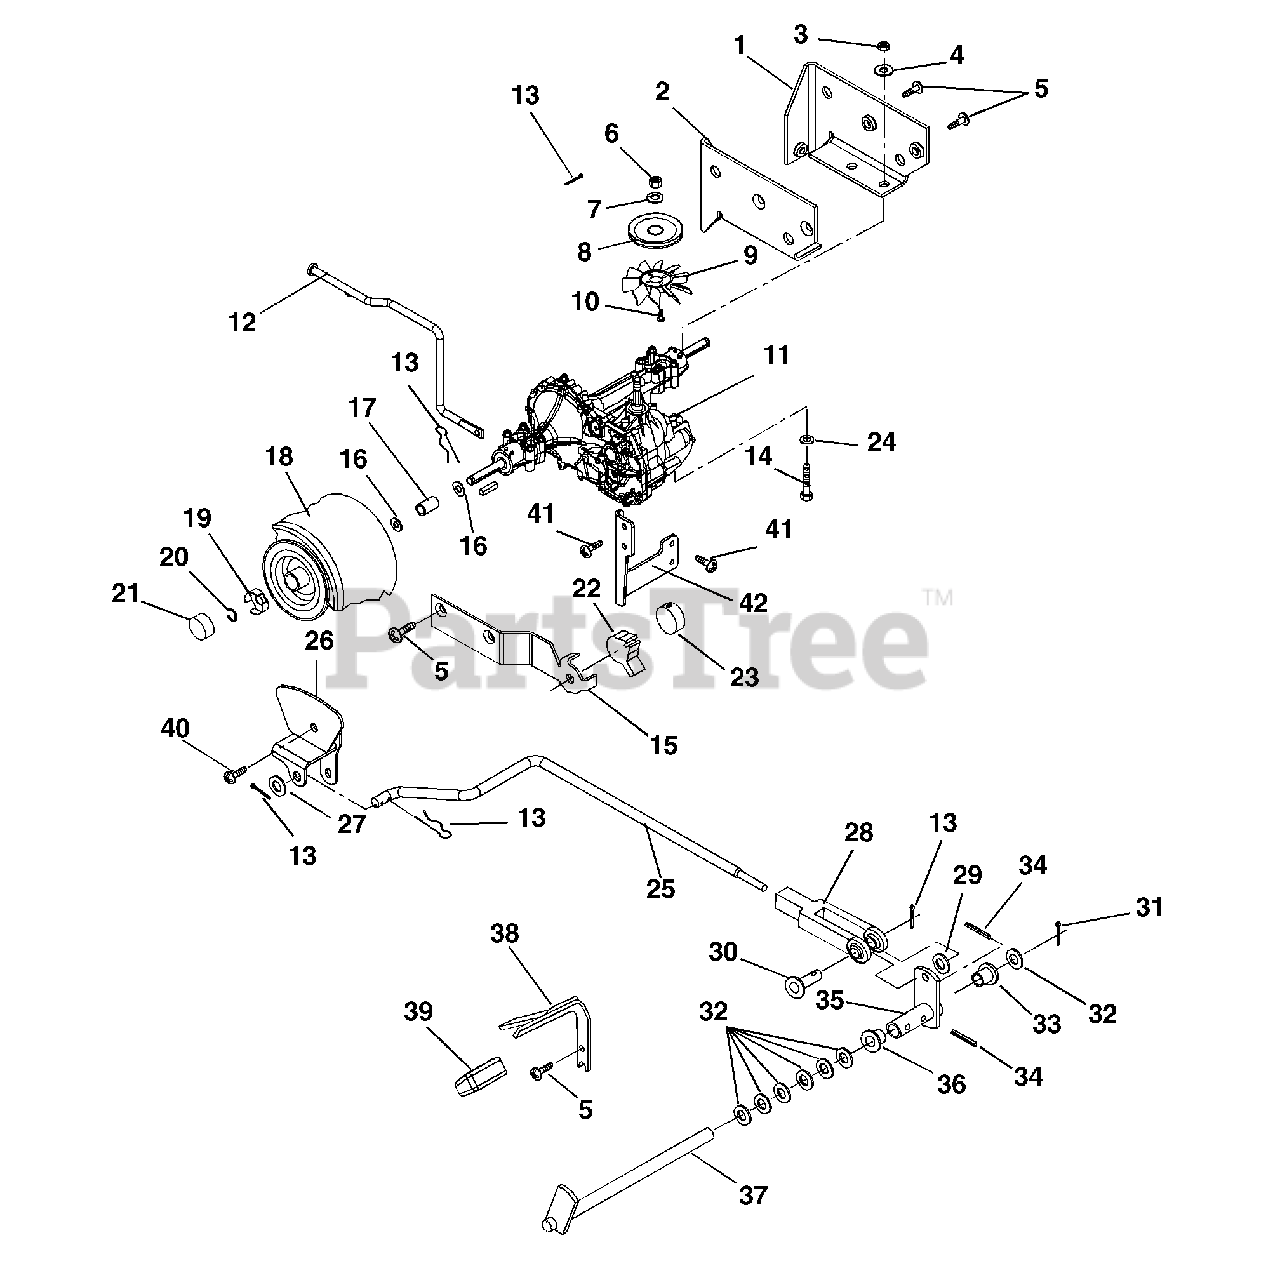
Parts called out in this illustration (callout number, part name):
1	TRANS MOUNT, LH
2	TRANS MOUNT, RH
3	@NUT-LK-CTR .31-18 YWZC
4	WSHR-FL-STL .328X.875X.062YWZC
5	@SCR-TAP .38-16X1.00 HWH TR YZ
6	NUT-JAM .50-20 GR2 YWZC
7	@WSHR-LK .50X.125 REG YWZC
8	SHEAVE - TRANSAXLE
9	FAN, TRANSMISSION (510)
10	SCR-TAP 10-24X.484 HWH TR
11	TRANSAXLE, HYDRO (510)
12	DISCONNECT, TRANS.
13	PIN-HAIR INT .08X.18X1.18 YWZC
14	@BLT-HEX .31-18X2.75 GR5 YWZC
15	KEY-SQ .188X2.0X.188 SAE 8630
16	WSHR-FL-STL.755X1.375X.062YWZC
17	SPACER, WHEEL .752X1.25X2.00
18	TIRE ASSEMBLY 20 X 10.00-8
18	RIM-SIERRA
18	TIRE 20X10-8 2P TS TL
19	SPINDLE CUP
20	RG-RTNG-EXT .750X.050
21	HUB CAP
22	MOUNT - MAGNET
24	@WSHR-FL-STL.344X.688X.065YWZC
25	ROD, SHIFT
26	BRACKET, SHIFTROD (WELDMENT)
27	@WSHR-FL-STL.406X.812X.065 YWZ
28	YOKE, .312-24 X 2.25
29	WSHR-FL-STL .390X.75X.125 YWZC
30	PIN-CLEV .312X.822 HDND PL
31	@PIN-CTR .12X1.00 EXTPRSQCT YZ
32	WSHR-FL-STL .52X.827X.062 YWZC
33	BSHG-FLG .515X.750X.745X1.00NY
34	PIN-GRV .188X1.25 TP A
35	ARM & HUB
36	BSHG-FLG .502X1X.750
37	SHAFT-PEDAL (SINGLE)
38	PEDAL-F/R SIERRA COMP
39	COVER - PEDAL - FORWARD
40	@SCR-TAP .31-18X.50 HWH TR YWZ
41	@SCR-TAP .38-16X.75 HWH TR YWZ
42	BRACKET, TRANS. SUPPORT
